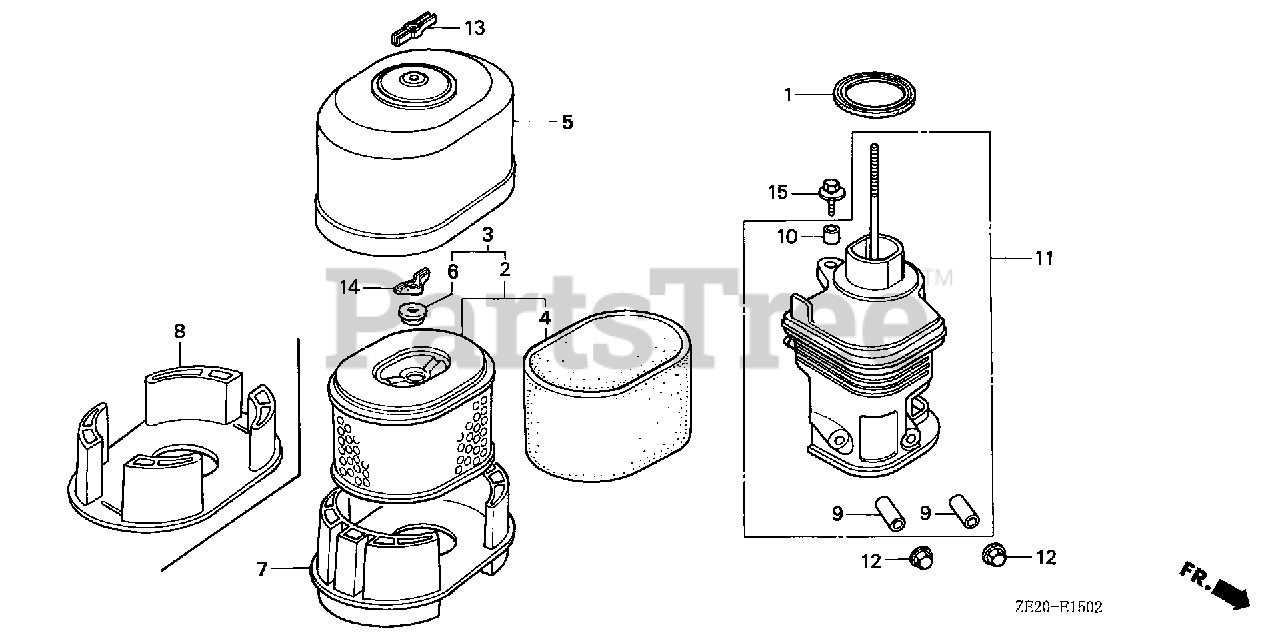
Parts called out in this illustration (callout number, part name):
1	GASKET, ELBOW
2	ELEMENT, AIR CLEANER (DUAL)
3	ELEMENT, AIR CLEANER (DUAL)
4	FILTER (OUTER)
5	COVER, AIR CLEANER (DUAL)
6	GROMMET, AIR CLEANER
9	COLLAR, AIR CLEANER
10	COLLAR B, AIR CLEANER
11	ELBOW, AIR CLEANER
12	NUT, CAP (6MM)
13	NUT, AIR CLEANER COVER (DACRO COATING)
14	NUT, TOOL BOX SETTING
15	BOLT-WASHER (6X20)
